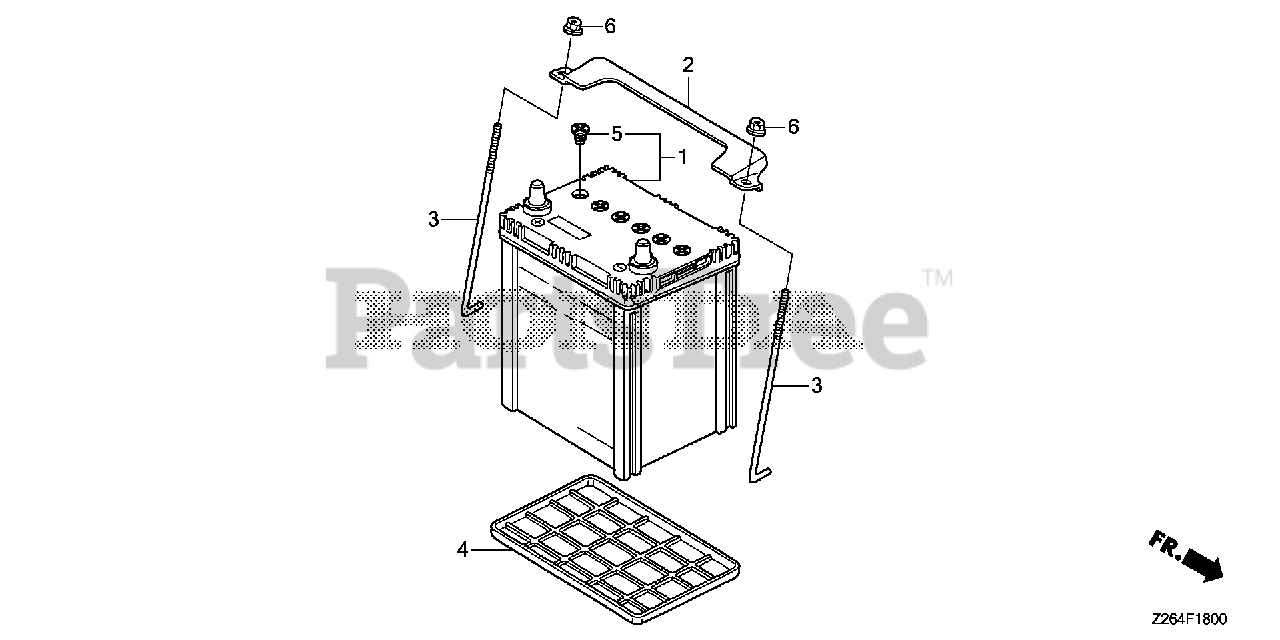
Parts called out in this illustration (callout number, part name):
1	BATTERY ASSY. (40B19R) (S) (MSDS)
1	BATTERY ASSY. (40B19R) (S)
2	PLATE, BATTERY SETTING
3	BOLT, BATTERY SETTING
4	BOX, BATTERY
5	PLUG, VENT (MF) (YUASA)
6	NUT, FLANGE (6MM)
